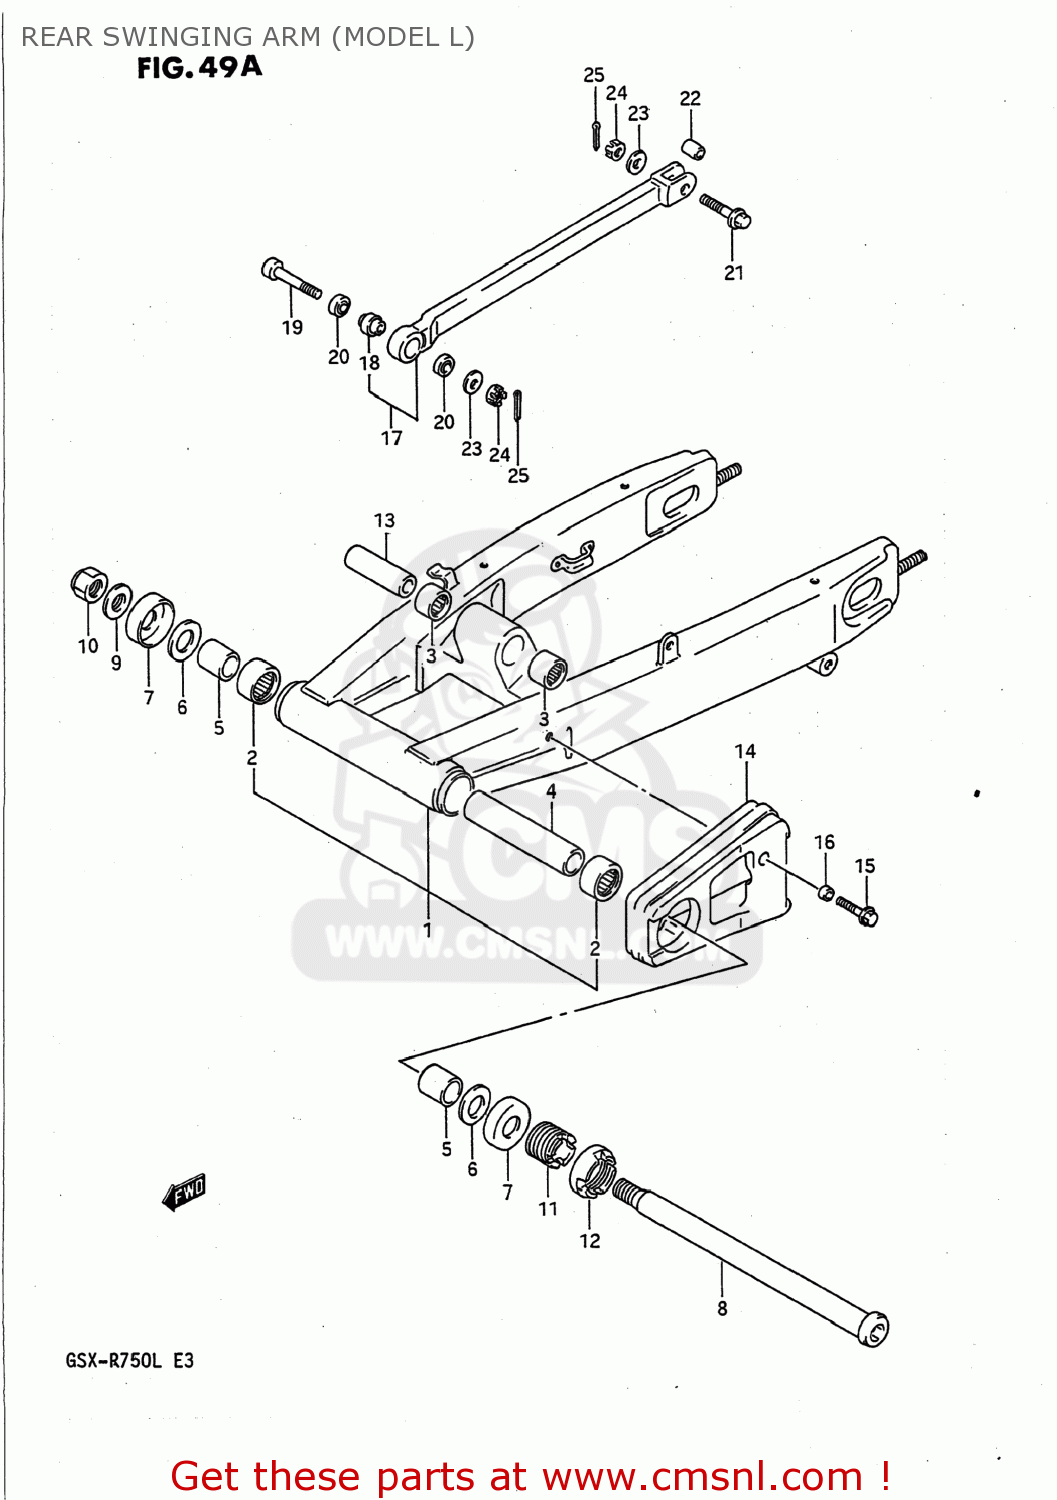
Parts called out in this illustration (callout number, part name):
1	SWING ARM ASSEMBLY,REAR
2	BEARING(25X33X30)
3	BEARING(20X27X23.5)
4	SPACER,RR SWGARM PIVOT CTR
5	SPACER,RR SWGARM PIVOT BERRING
6	WASHER
7	DUST SEAL,RR SWGARM PIVOT
8	SHAFT,REAR SWING ARM PIVOT
9	WASHER
10	NUT
11	BOLT,RR SWGARM PIVOT
12	NUT,REAR SWING ARM PIVOT
13	SPACER,RR CUSHION LEVER
14	BUFFER,CHAIN TOUCH DEFENSE
15	BOLT 6X20,WITH PLAIN WASHER
16	SPACER
17	TORQUE LINK SET,REAR
18	SPHERICAL BEARING,TORQUE
19	BOLT(8X48)
20	21
21	BOLT(8X38)
22	SPACER,RR TORQUE LINK RR
23	WASHER
24	NUT 8MM
25	PIN 20X20
